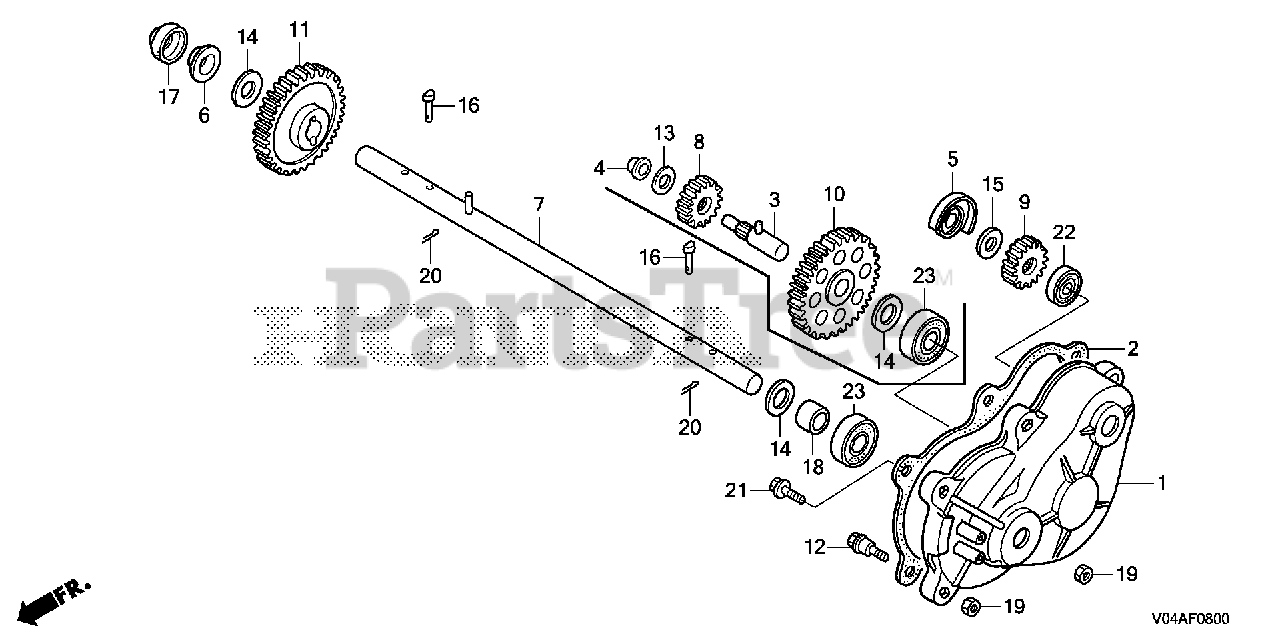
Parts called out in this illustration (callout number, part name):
1	CASE, R. TRANSMISSION
2	GASKET, TRANSMISSION CASE
3	COUNTERSHAFT
4	BUSH, COUNTERSHAFT
5	BUSH, CROSS SHAFT
6	BUSH, FINAL SHAFT
7	SHAFT, WHEEL
8	GEAR, FINAL DRIVE (15T)
9	GEAR, DRIVE (19T)
10	GEAR, DRIVEN (48T)
11	GEAR, FINAL DRIVEN (38T)
12	BOLT, TRANSMISSION SETTING
13	WASHER, THRUST (12MM)
14	WASHER, DIFFERENTIAL GEAR
15	WASHER, THRUST (15X24X2)
17	DUST SEAL (20X34X7.5)
18	COLLAR, WHEEL SHAFT
19	NUT, HEX. (6MM)
20	PIN, SPLIT (3.0X25)
20	PIN, SPLIT (3.0X45)
21	BOLT, FLANGE (6X18)
22	BEARING, RADIAL BALL (6002UU)
23	BEARING, RADIAL BALL (6004UU)
